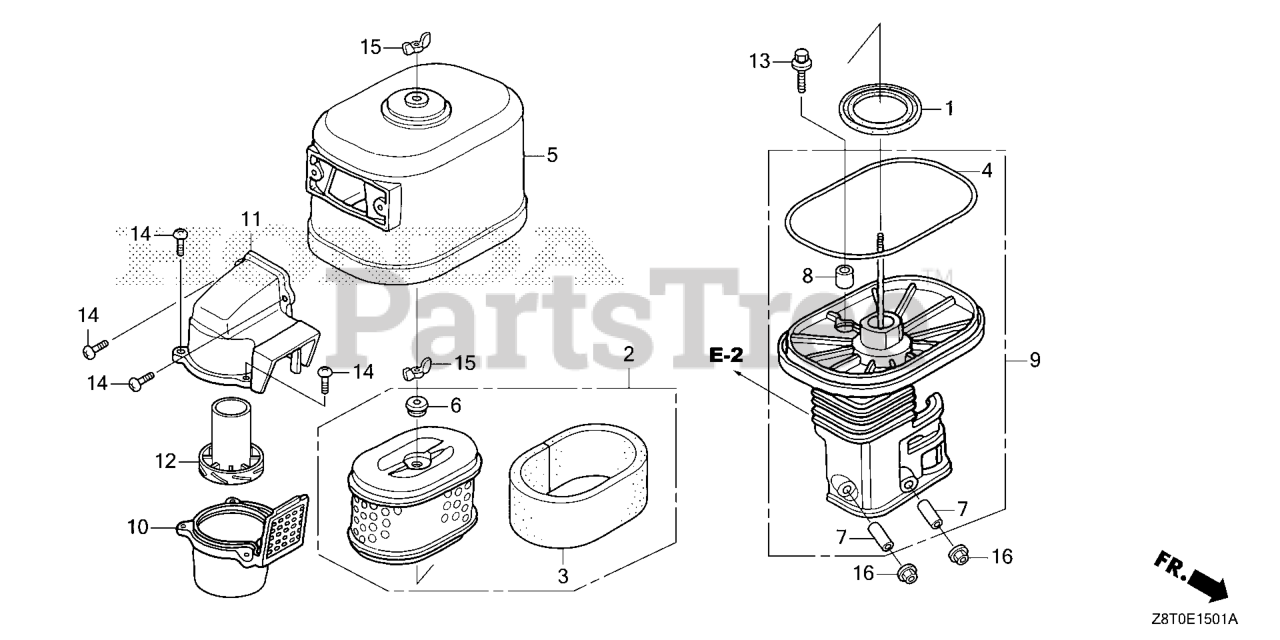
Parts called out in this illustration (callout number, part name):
1	GASKET, ELBOW
2	ELEMENT, AIR CLEANER
3	FILTER (OUTER)
4	SEAL, AIR CLEANER COVER
5	COVER, AIR CLEANER (CYCLONE)
6	GROMMET, AIR CLEANER
7	COLLAR, AIR CLEANER
8	COLLAR B, AIR CLEANER
9	ELBOW, AIR CLEANER
10	CASE, PRE AIR CLEANER
11	CAP, PRE AIR CLEANER
12	GUIDE, PRE AIR CLEANER
13	BOLT-WASHER (6X22)
14	SCREW, PAN (5X16.5)
15	WINGNUT, TOOL BOX SETTING
16	NUT, FLANGE (6MM)
